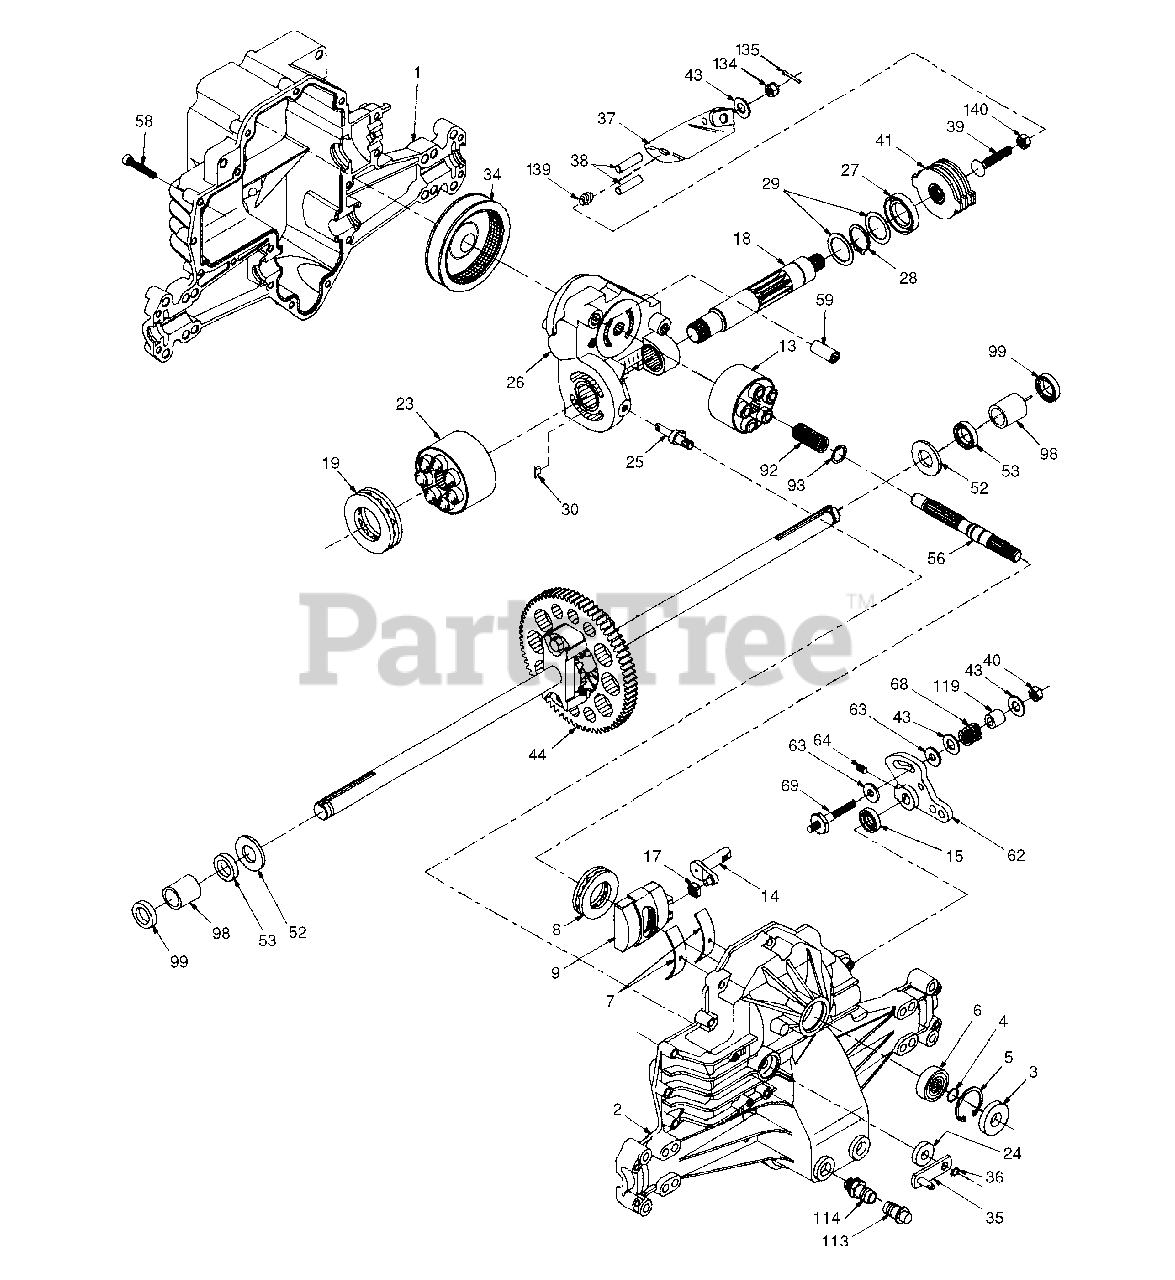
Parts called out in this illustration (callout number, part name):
1	Housing, Lower
2	Assembly, Upper Housing
4	Ring, Wire Retaining
5	Ring, Retaining
6	Bearing, Shaft Ball
7	Bearing, Cradle
8	Bearing, Thrust 30 x 52 x 13
9	Swashplate, Variable
13	Block, Cylinder Assembly
14	Arm, Trunnion
17	Guide, Slot
18	Shaft, Motor
19	Bearing, Thrust 42 x 68 x 16
23	Block, Cylinder Assembly
24	Seal, Lip 10 x 25 x 7
25	Actuator, Bypass
26	Center Section Assembly Kit
27	Seal, Lip 26 x 42 x 8
28	Ring, Retaining
29	Washer 26 x 35 x 1
34	Oil Filter Element
35	Arm, Bypass
36	Ring, Retaining
37	Arm, Actuating
38	Pin, Actuating
39	Bolt 5/16-24 x 1-3/4
40	Locknut, Hex 5/16-24 UNJC
41	Brake Rotor/Stator Kit
43	Washer 7/16 x 7/8 x .060
44	Differential Assembly
52	Washer 3/4 x 1.5 x .13
53	Seal .75 x 1.25 x .250
56	Shaft, Input
58	Bolt 1/4-20 x 1.38
59	Pin .5 OD x .43 ID x .750
62	Arm, Control
63	Puck, Dampener
69	Stud 5/16-24
92	Spring, Block
93	Washer, Block Thrust
98	Sleeve Bearing
99	Seal, Wiper
113	Cap, Vent Assembly
114	Fitting, O-Ring Assembly
119	Spacer
134	Nut, Castle 5/16-24
135	Pin, Cotter
139	Spring, Compression
140	Nut, Hex 5/16-24
